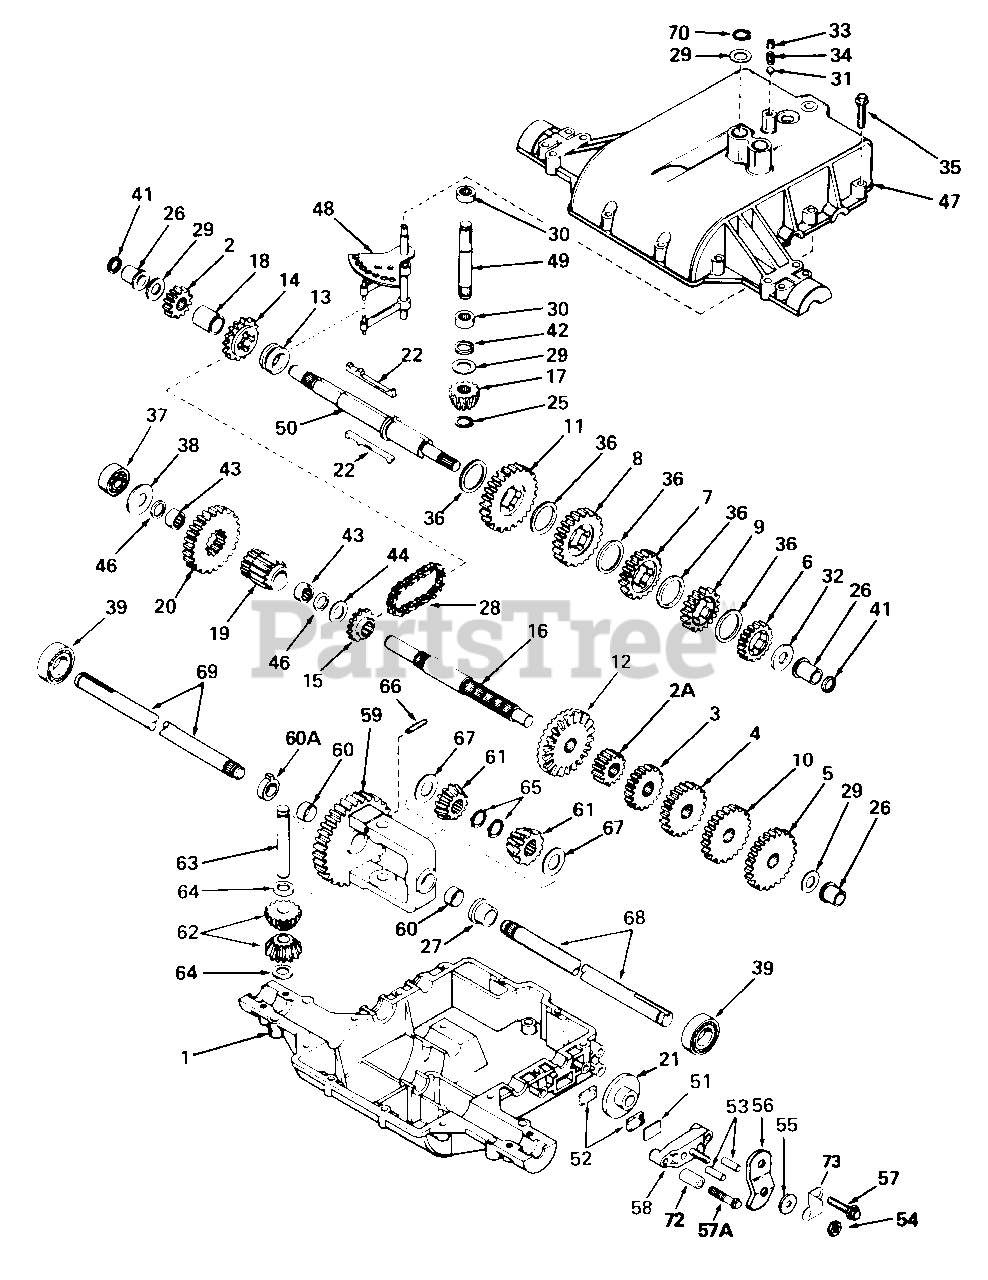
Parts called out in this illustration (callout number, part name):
1	CASE, Transaxle
2	GEAR, Spur (15 teeth)
2A	GEAR, Spur (12 teeth)
3	GEAR, Spur (20 teeth)
4	GEAR, Spur (25 teeth)
5	GEAR, Spur (30 teeth)
6	GEAR, Spur (20 teeth)
7	GEAR, Spur (25 teeth)
8	GEAR, Spur (30 teeth)
9	GEAR, Spur (22 teeth)
10	GEAR, Spur (28 teeth)
11	GEAR, Spur (37teeth)
12	GEAR, Bevel (42 teeth)
13	COLLAR, Shift
14	SPROCKET (14 teeth)
15	SPROCKET (10 teeth)
16	SHAFT, Counter
17	BEVEL PINION, Input
19	PINION, Output
20	GEAR, Output
21	DISK, Brake
25	RING, Retaining
26	BUSHING, Flanged
27	BUSHING, Flanged
28	CHAIN, Roller (No. 41 chain, 22 links)
29	WASHER, Thrust
30	BEARING, Needle
31	BALL, Steel
32	WASHER, Thrust
33	SCREW, Set, 3/8-16 x 3/8
35	SCREW, Hex Hd., Thd. Form., 1/4-20 x 1-1/4
36	WASHER, Thrust
37	BEARING, Ball
38	WASHER, Flat
39	BEARING, Ball
41	SEAL, Square Cut
42	SEAL, Square Cut
43	BEARING, Needle
44	WASHER, Flat
46	SEAL, Square Cut
47	COVER, Transaxle
48	ROD & FORK ASSY., Shift
49	SHAFT, Input
50	SHAFT, Brake
51	PLATE, Brake Pad
52	PAD, Brake
53	PIN, Dowel
54	LOCKNUT, 5/16-24
55	WASHER, Flat
56	LEVER, Brake
57	SCREW, Hex Hd., Thd., Form., 1/4-20 x 1-1/4
57A	SCREW, Hex Hd., Thd., Form., 1/4-20 x 2-1/4
58	HOLDER, Brake Pad
59	GEAR ASSY., Differential (Incl. 2 of No. 60)
61	GEAR, Bevel
62	PINION, Bevel
63	PIN, Drive
64	WASHER, Thrust
65	RING, Retaining (Pkg. of 2)
66	PIN, Roll
67	WASHER, Thrust
68	AXLE (15-1/2" long)
69	AXLE (12-1/2" long)
70	RING, Retaining
